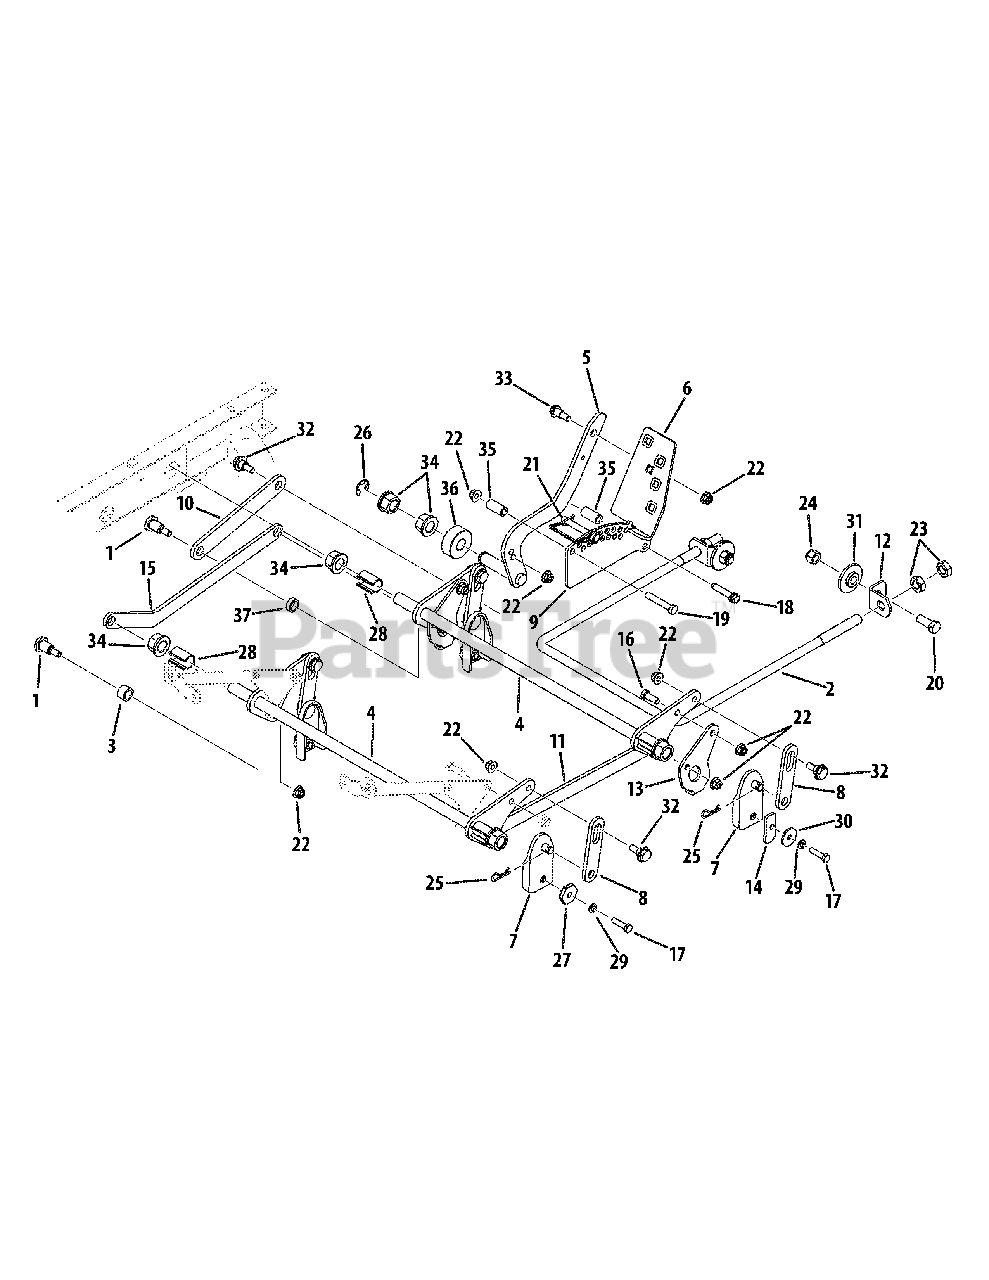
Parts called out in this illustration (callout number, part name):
1	Shoulder Screw, .625 x .830
3	Spacer, .632 x .877 x .548
5	Foot Lift Pivot Assembly
6	Lift Pedal Assembly
6	Lift Pedal Service Kit
6	Torsion Spring
6	Screw .50X.925
7	Deck Lift Adjustment Bracket
12	Front Hanger Rod Bracket Mount
13	Deck Up Stop Bracket
14	Deck Lift Square Spacer
15	Mid-Angled Link Plate
16	Hex Screw, 3.8-16 x 1.00
17	Hex Screw, 5.16-18 x 1.25
18	Hex Washer Screw, 3.8-16 x 1.875
19	Hex Screw, 3.8-16 x 2.25
20	Hex Screw, 1.2-13 x 1.25
21	Lock Pin, .375 x 2.25
22	Flange Lock Nut, 3.8-16
23	Jam Nut, 5.8-11
24	Hex Lock Nut, 1.2-13
25	Click Pin, .092 x 1.64
26	E-Type Ring, .750
27	Adjustable Deck Gear
28	Spacer, .791 x .950 x 1.35
29	Lock Washer, 5.16
30	Flat Washer, .330 x 1.25 x .120
31	Shoulder Spacer, .9790 x .2025
32	Shoulder Spacer, 3.8-16 x .562 x .360
33	Shoulder Screw, 3.8-16 x .50 x .50
34	Hex Flange Bearing, .752
35	Spacer, .375 x .625 x 1.290
36	Spacer, .760 x 2.000 x .790
37	Spacer, .632 x .877 x .281
